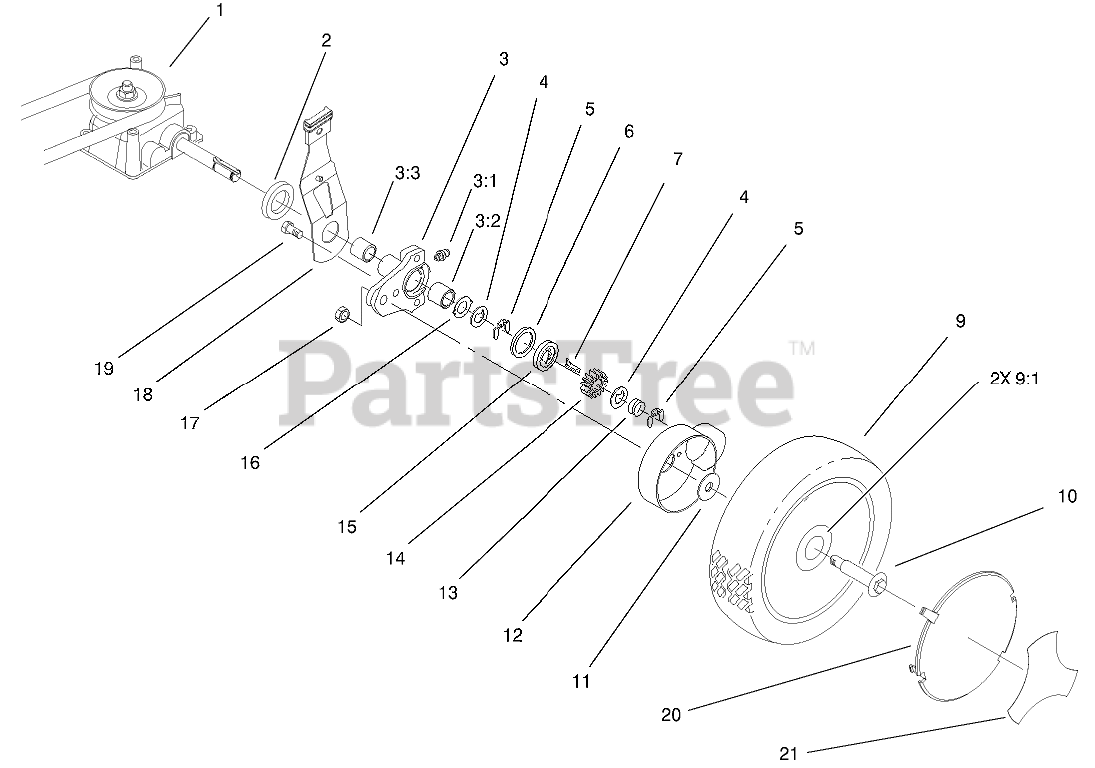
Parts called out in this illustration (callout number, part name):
1	V-BELT
2	SPACER-AXLE SHAFT
3	REAR HEIGHT ADJUSTMENT ARM ASM
3:1	FITTING-GREASE
3:2	BUSHING
3:3	BUSHING
4	WASHER-THRUST, KEYED
5	RING-CLIP, LOCKING
6	RING-FRICTION
7	KEY-ROCKING, RH
9	WHEEL ASM
9:1	BUSHING
10	BOLT-SHOULDER
11	WASHER-STEPPED
12	COVER-WHEEL
13	SPRING-COMPRESSION
14	GEAR-PINION
15	WASHER-CLUTCH
16	WASHER-ARM, PIVOT
18	REAR SPRING ARM ASM
19	SCREW-HWH
20	COVER-WHEEL, SMART
21	LABEL-WHEEL, SMART
